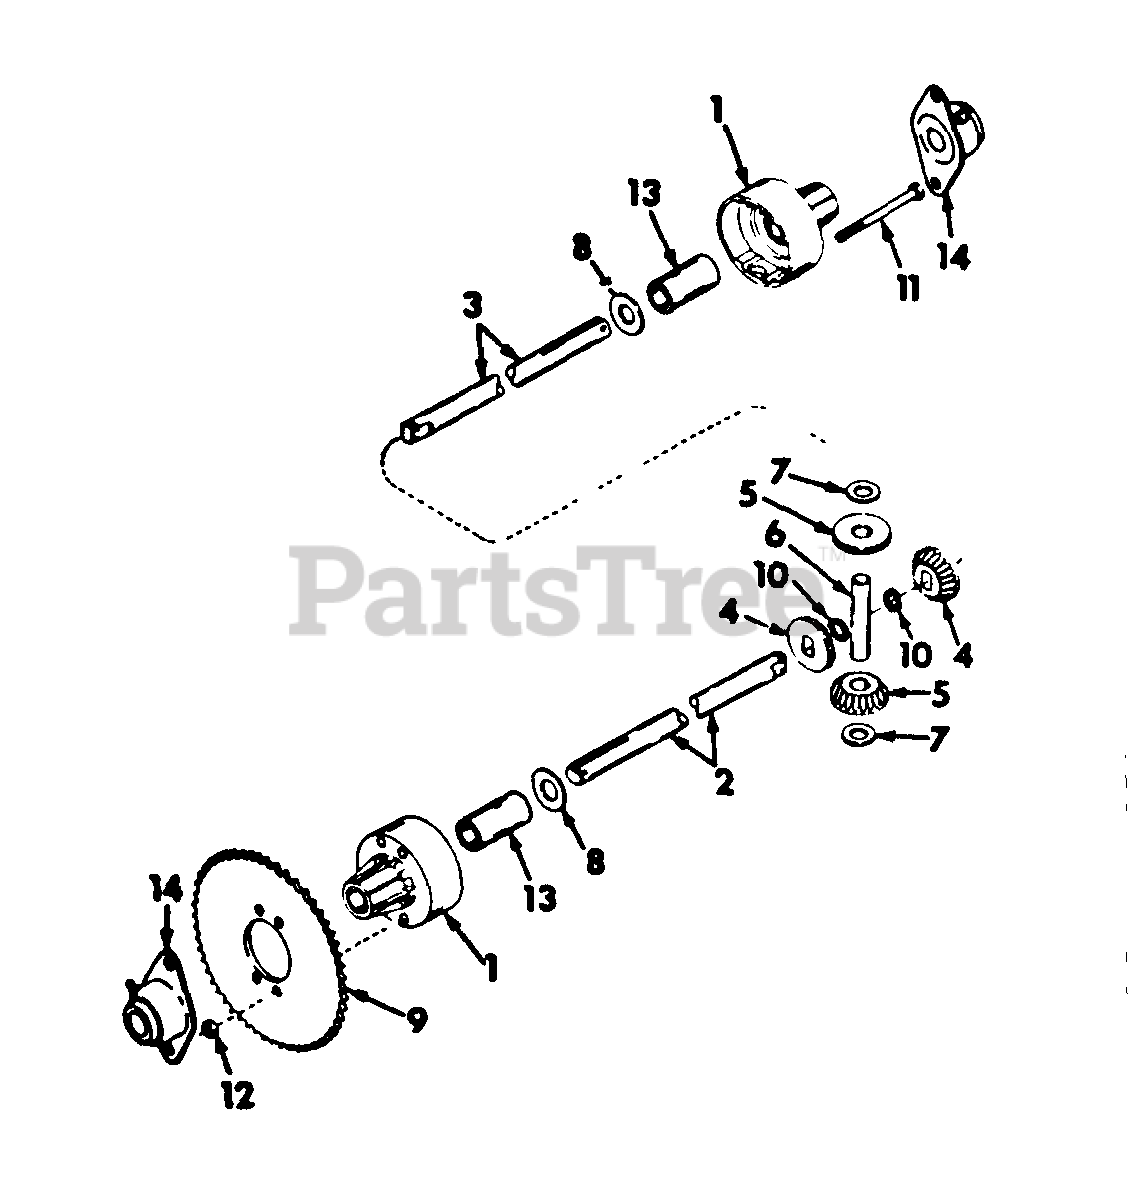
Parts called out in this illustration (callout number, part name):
1	HOUSING W/BUSHING, DIFFERENTIAL CARRIER -SPROCKET SIDE-
4	GEAR, BEVEL -16 T
5	GEAR, PINION -16 T
7	WASHER, THRUST BRG RACE
9	SPROCKET, 45 T
10	RING RETAINER
11	SCREW, 5/16-18 SPECIAL
12	NUT, 5/16-18 LOCK
14	BEARING, REAR AXLE
